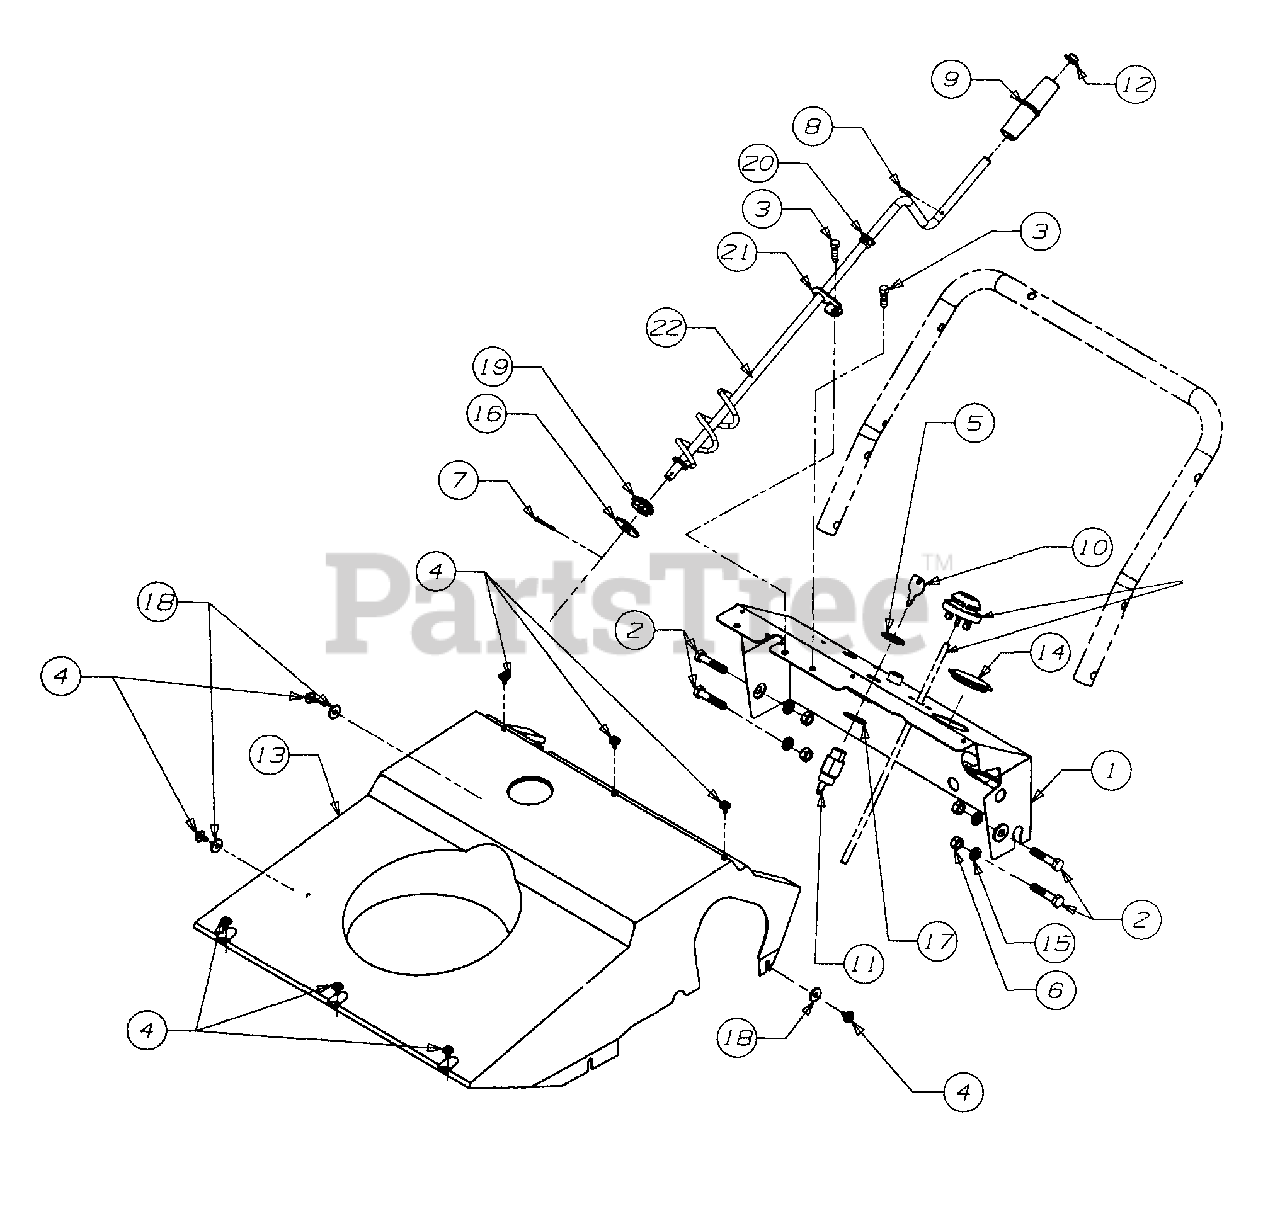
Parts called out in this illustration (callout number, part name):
3	Screw - Hex Tap
4	Screw - Hex Tap
6	Nut - Hex
7	Pin - Cotter
8	Pin Roll
9	Knob - Chute Crank
10	Key - Ignition
11	Switch - Key
15	Washer Lock
16	Washer Flat
17	Washer internal Lock
18	Washer Flat
19	Bushing Hex
20	Bushing
21	Bracket Chute Crank
22	Crank Ass'y. Chute
